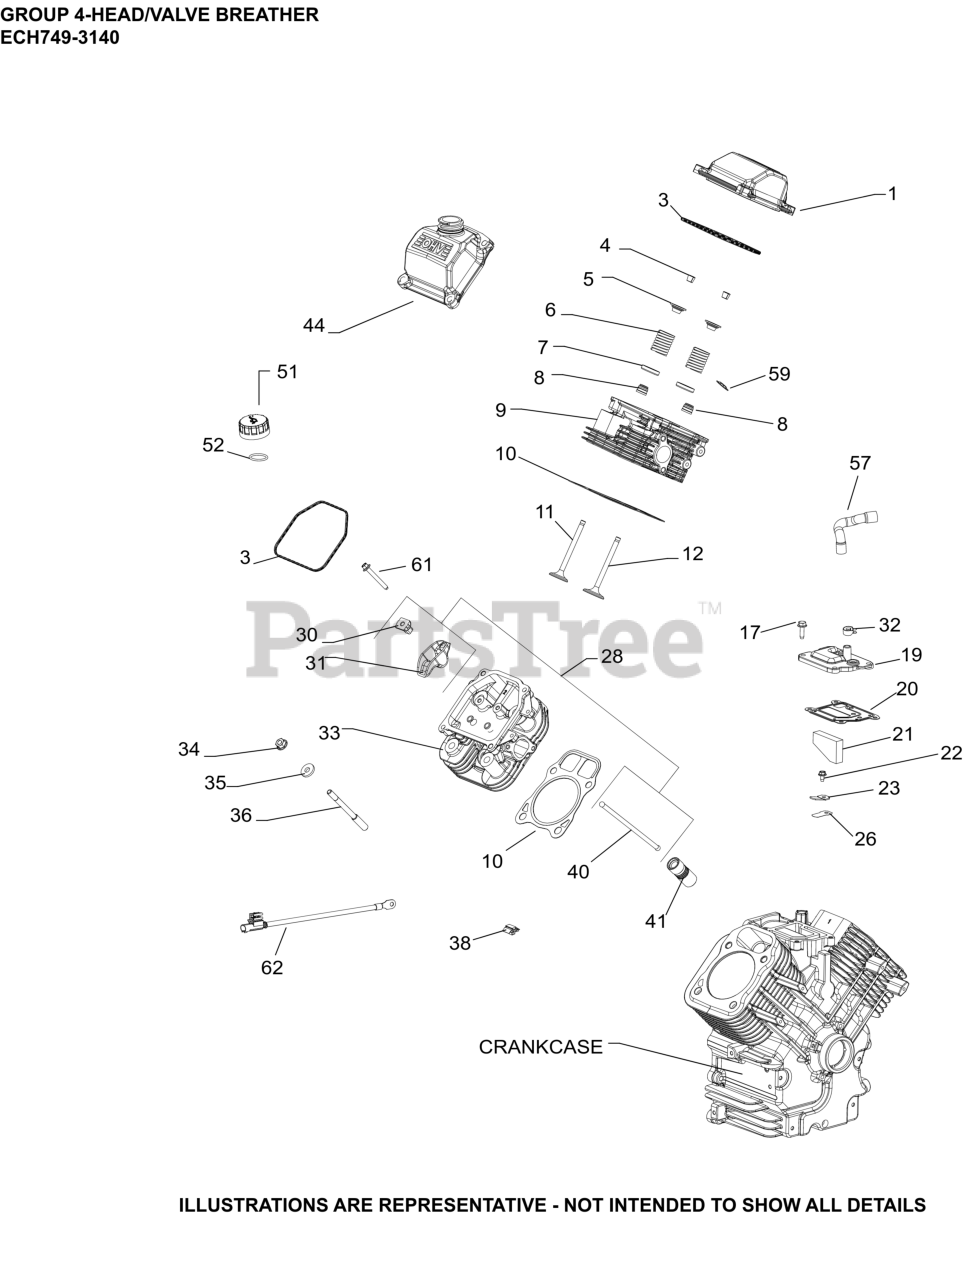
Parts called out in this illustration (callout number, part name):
1	KIT, VALVE COVER-PLAIN (PLASTIC)
3	O-RING (YELLOW), VALVE CO
4	KIT, RETAINER
5	CAP, VALVE SPRING
6	SPRING, VALVE
7	RETAINER, SPRING
8	SEAL, VALVE BAND
9	KIT, CYLINDER HEAD (#1)-(#2481803S)
10	KIT, GASKET CYLINDER HEAD
11	VALVE, EXHAUST
11	VALVE, EXHAUST (.25)
12	VALVE, INTAKE (STD)
12	VALVE, INTAKE (.25)-(#DSC)
17	SCREW, THREAD FORMING
19	COVER, BREATHER
20	GASKET, BREATHER
21	FILTER, BREATHER
22	SCREW, FLG THD FRM M5X.8X10
23	RETAINER, REED
26	REED, BREATHER
28	KIT, VALVE TRAIN
30	PIVOT, ROCKER ARM
31	ARM, ROCKER
32	SPRING CLAMP, HOSE
33	KIT, CYLINDER HEAD (#2)-(#2481804S)
34	NUT, FLG M8X1.25
35	WASHER, FLAT 8.6 MM
36	STUD, M8X1.25
38	CLIP, O2 SENSOR
40	ROD, PUSH
41	LIFTER, VALVE HYDRAULIC-USE 25 351 11-S
44	KIT, VALVE COVER-OIL FILL
51	KIT, OIL FILL CAP (YELLOW)
52	O-RING, DIPSTICK
57	HOSE, BREATHER (ETB HORIZONTAL)
59	RETAINER, VALVE GUIDE (KM)
61	SCREW, HEX FLANGE
62	LEAD, SENSOR TEMPERATURE
NI	SCREW, HEX FLANGE (M6 X 31.625 DOG PT)
